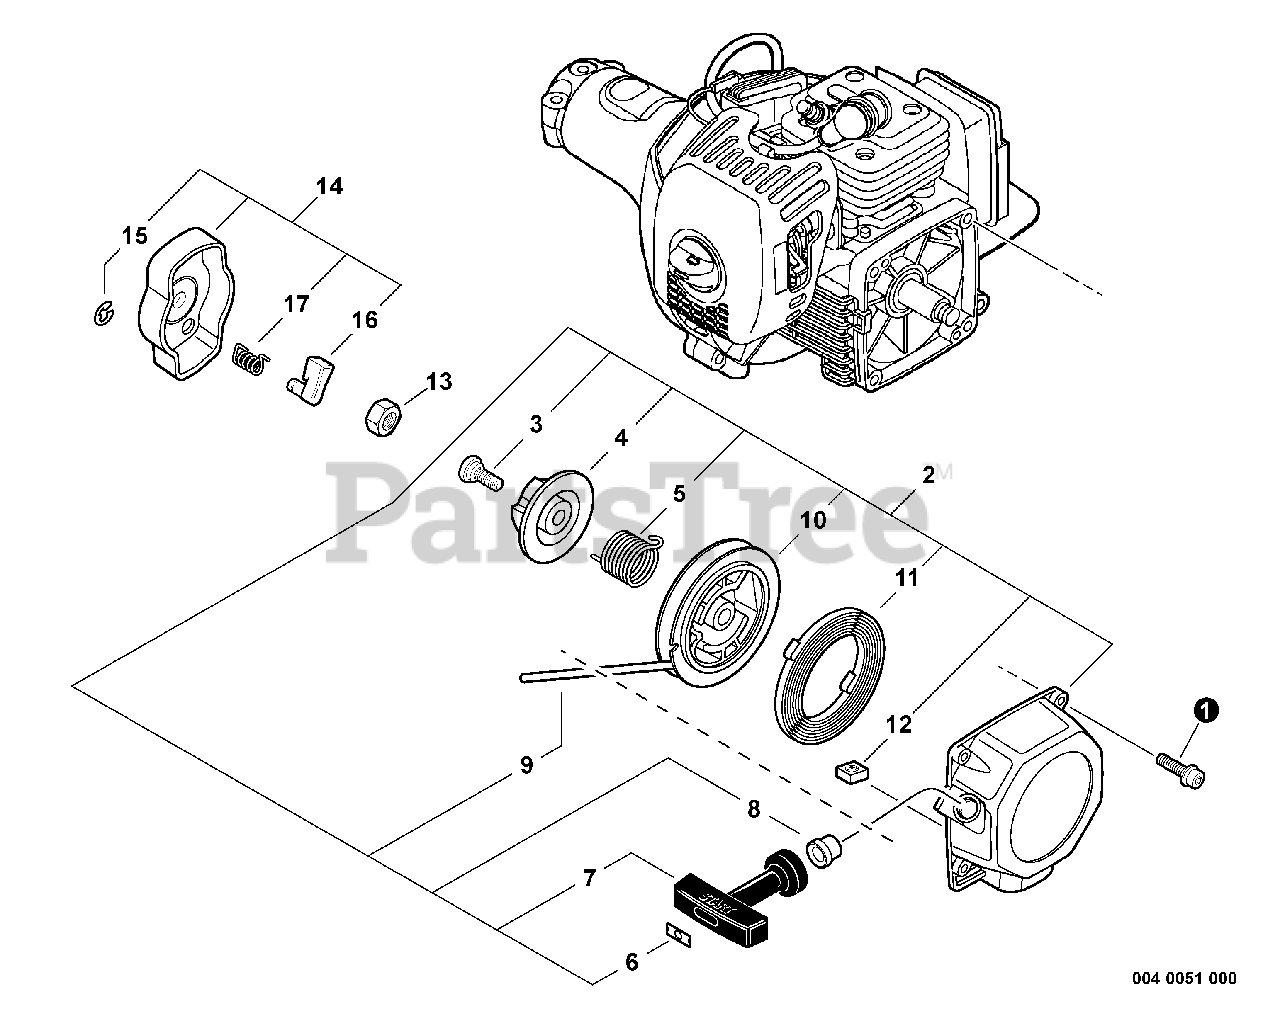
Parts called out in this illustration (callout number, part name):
1	SCREW 5×16
2	STARTER ASSY
3	SCREW
4	PLATE, CAM (NLA SEE PB 15-06)
5	SPRING, TORSION
6	RETAINER, ROPE
7	GRIP, STARTER
8	GUIDE, ROPE
9	ROPE, STARTER 3×700
10	REEL, ROPE
11	SPRING, RECOIL
12	NUT M5
13	NUT 8×1.25
14	PAWL ASSY, STARTER
15	E-RING 4
16	PAWL, STARTER
17	SPRING, RETURN
